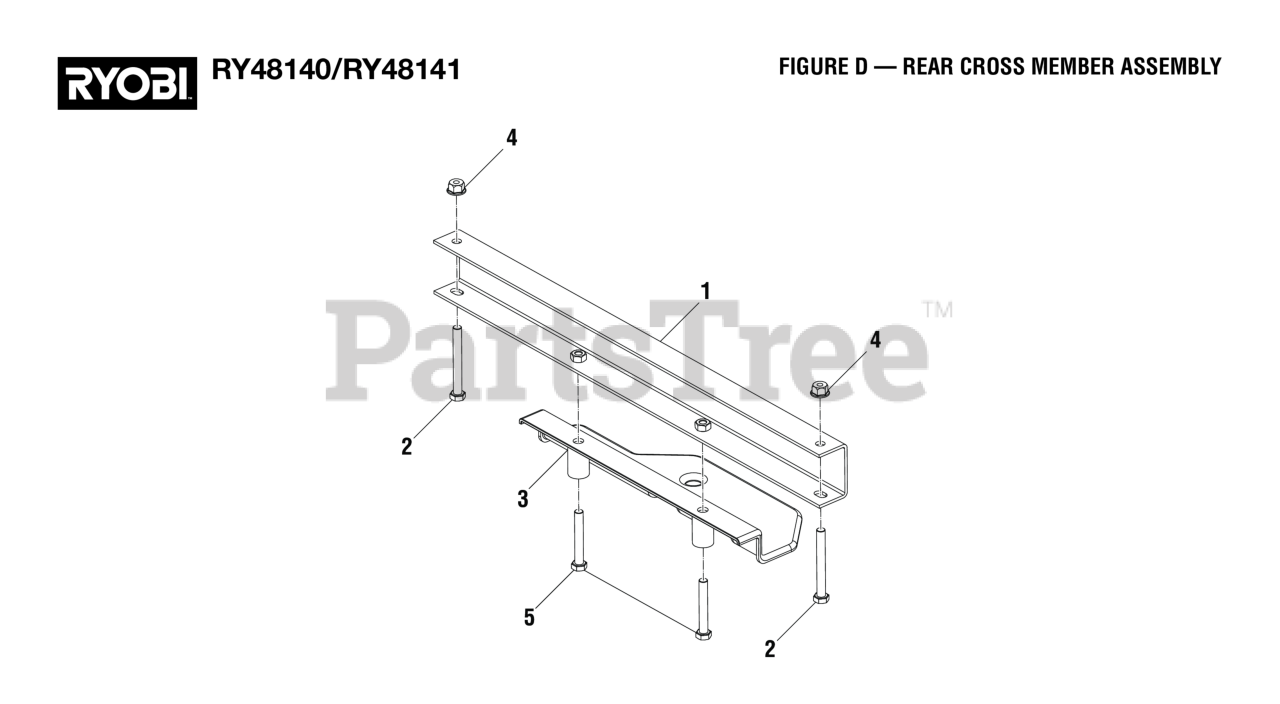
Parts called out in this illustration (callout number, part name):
1	Rear Cross Member, Frame
2	Bolt (M8 x 70 mm, Hex Hd.)
3	Tow Hitch
4	Flange Nut (M8) (For Drive Motor Controller V)
5	Bolt (M8 x 55 mm, Hex Hd.)
